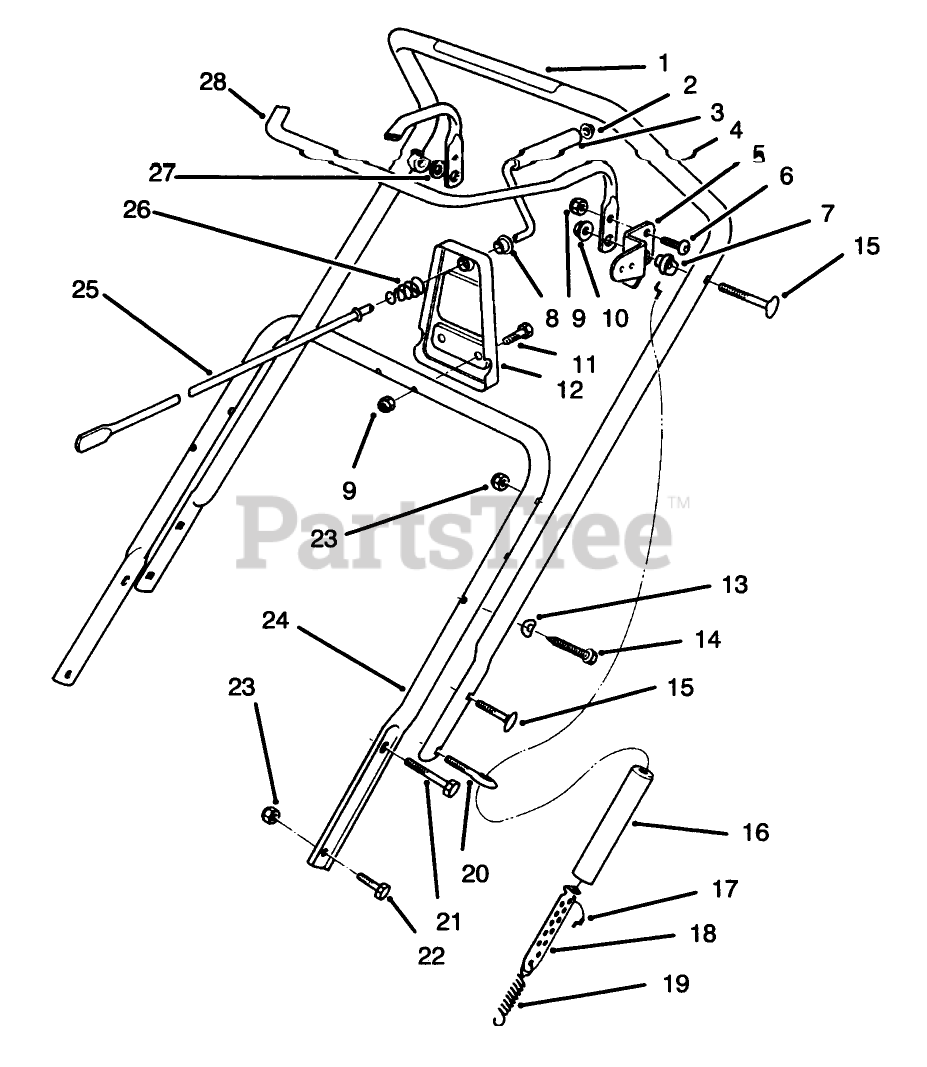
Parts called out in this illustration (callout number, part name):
1	DECAL - ROTOR DRIVE
2	RETAINER-PUSH ON
3	GRIP-CONTROL, CHUTE
4	Upper Handle Assembly (Incl. ref. #1, Model 38185)
5	Arm-Clutch Cable
6	SCREW-HSBH
7	SPACER-BAR, CONTROL
8	NUT-LOCK, CAP
9	NUT-LOCK, NI
10	Bushing
11	SCREW-HH
12	Support-Crank
13	WASHER
14	SCREW
15	SCREW
16	COVER-SPRING
17	CABLE-CLUTCH
18	ADJUSTER-CABLE
19	SPRING-EXTENSION
20	BOLT-EYE
21	SCREW-HH
22	SCREW-HH
23	NUT-LOCK, NI
24	Handle-Lower (Model 38180)
25	ROD-CRANK, CHUTE
26	SPRING-COMPRESSION
27	WASHER
28	Bar-Control
